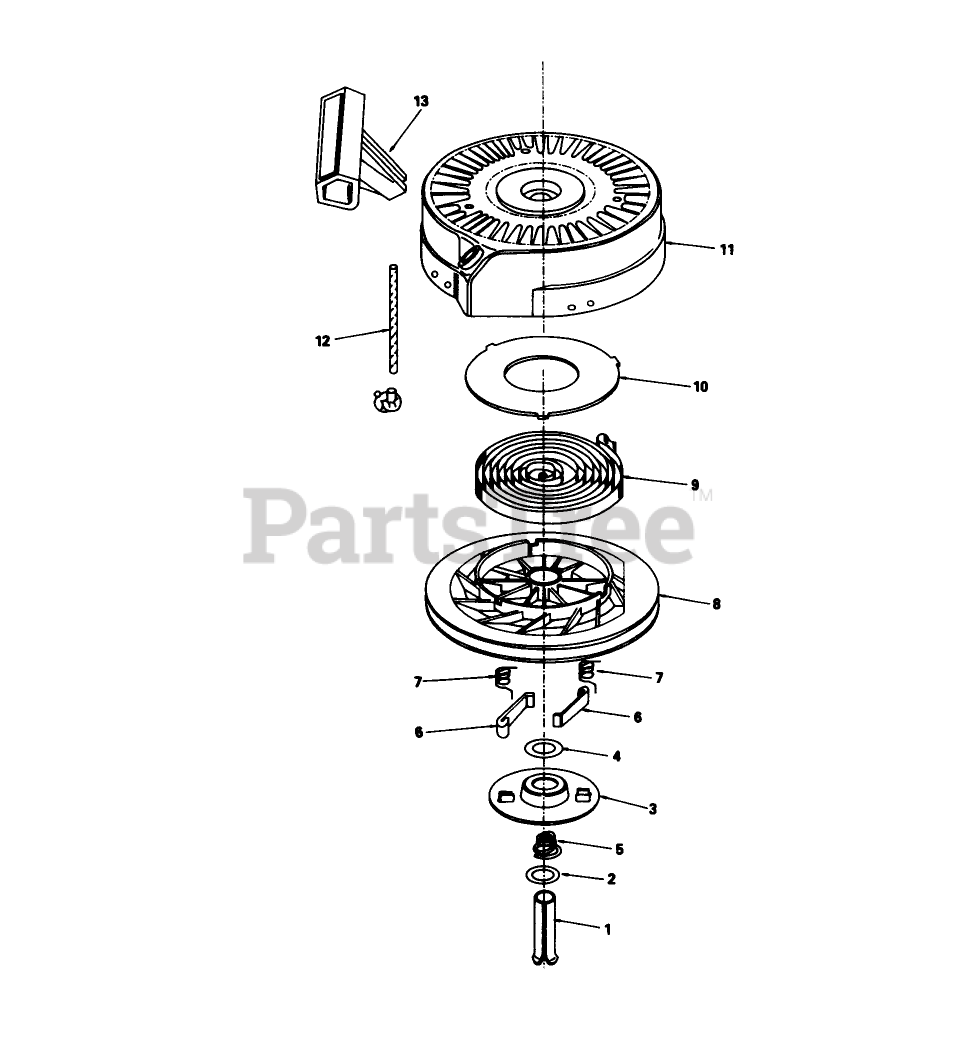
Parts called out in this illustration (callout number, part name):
1	Pin, Spring (Incl. Ref. #7)
2	Washer
3	Retainer
4	Washer
5	Brake Spring
6	Dog-Starter
7	Spring-Dog
8	Pulley
9	Rewind Spring
10	Cover-Spring
11	Housing-Starter
12	Rope-Starter (98 cut to length)
13	Handle-Starter
